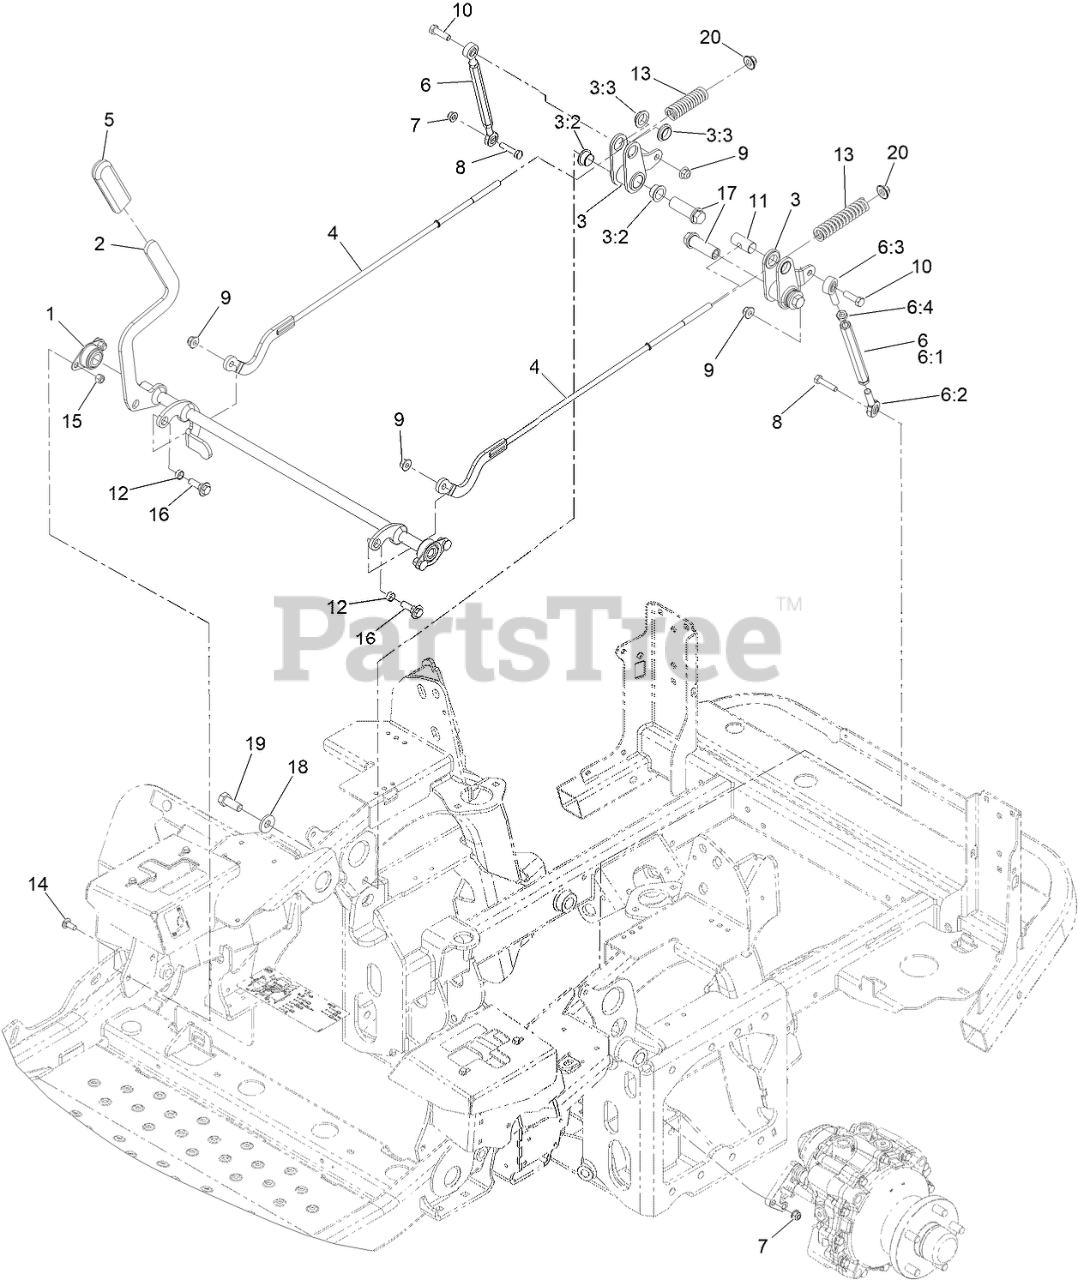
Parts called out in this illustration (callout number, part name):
1	BEARING-FLANGE, SIDE
2	SHAFT-BRAKE
3	BRAKE BELLCRANK ASM
3:2	BUSHING-FLANGE
3:3	BUSHING-FLANGE
4	LINK-BRAKE, UPPER
5	GRIP-LEVER
6	TURNBUCKLE ASM
6:1	TURNBUCKLE
6:2	BEARING-END, LH ROD
6:3	BALLJOINT
6:4	NUT-HJ
7	NUT-HF, NI
8	SCREW-HH
9	NUT-HF, NI
10	SCREW-HH
11	PIN-TRUNION
12	BEARING-SLEEVE
13	SPRING-COMPRESSION
14	SCREW-CARR
15	NUT-LOCK, NI
16	SCREW-SHOULDER, HWH
17	HUB-THREADED
18	WASHER-SPRING
19	SCREW-HH
20	Nut-Nyloc 3/8-16 Flg
